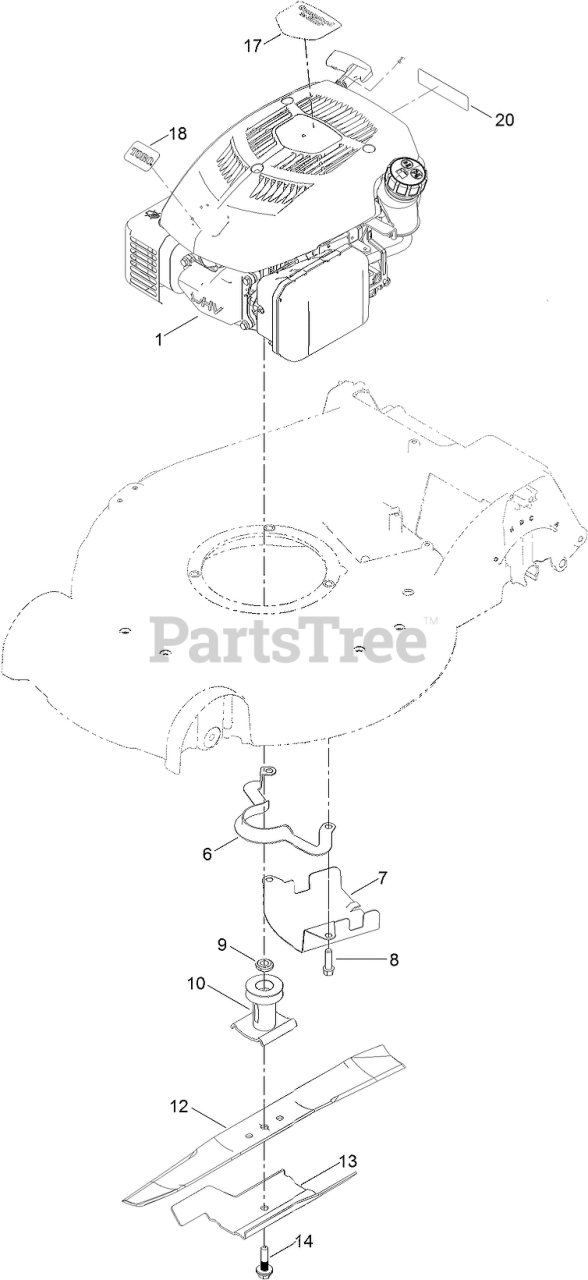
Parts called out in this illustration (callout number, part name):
1	ENGINE-1P65F-2
6	GUIDE-BELT
7	SHIELD-GRASS
8	SCREW-TAPTITE
9	SPACER-DRIVER
10	DRIVER-BLADE
12	BLADE-21IN, RECYCLING
13	ACCELERATOR-BLADE
14	BOLT-BLADE
17	DECAL-SHROUD
20	DECAL-ARRESTOR, SPARK
